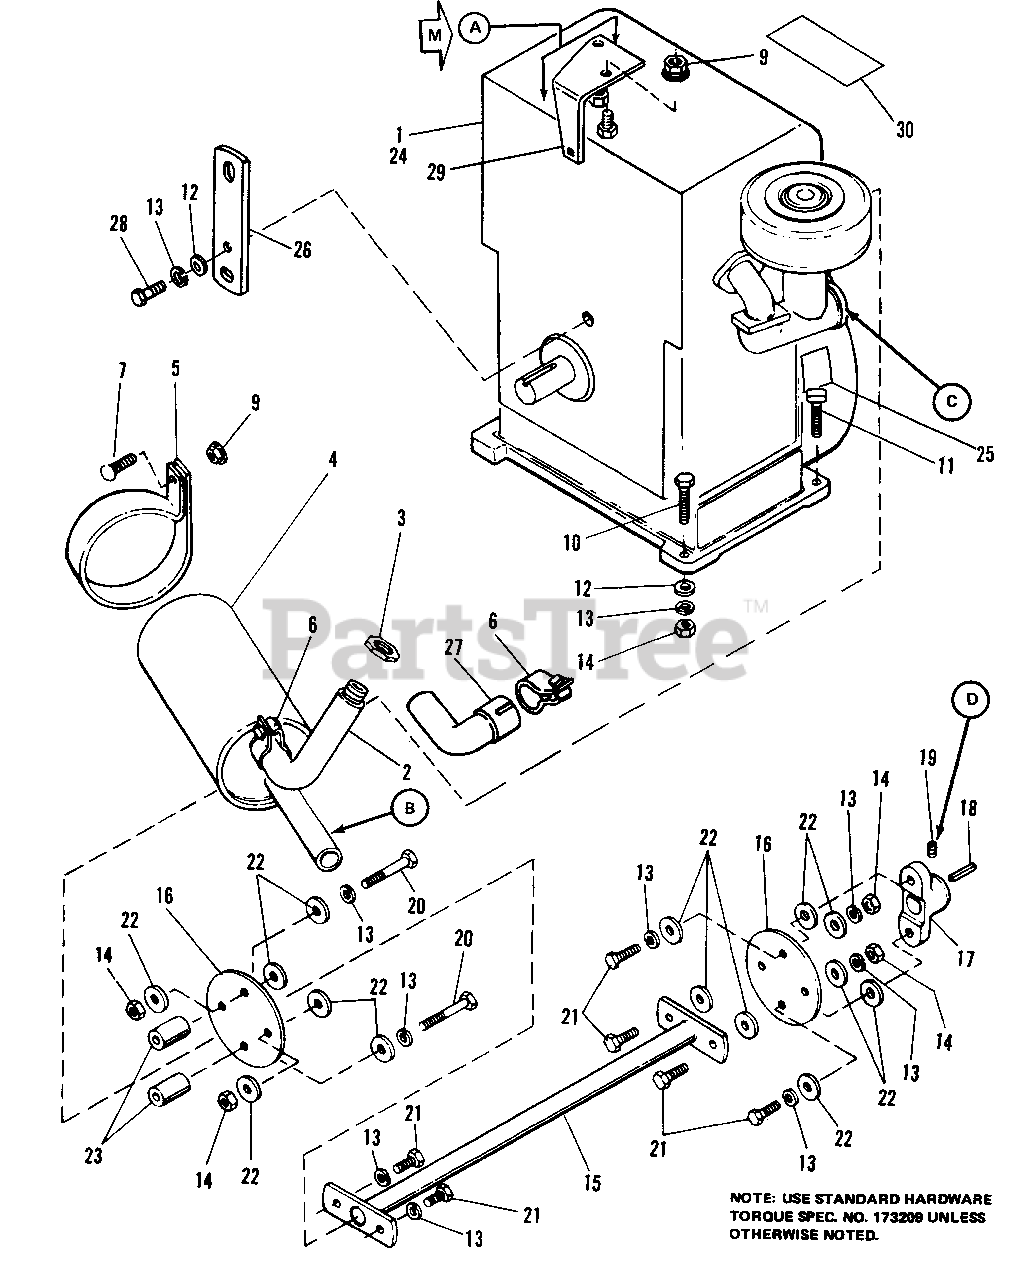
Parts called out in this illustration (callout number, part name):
1	ENGINE, 12 H.P., Kohler (7012 Only)
2	ELBOW & NIPPLE ASSY (7016 Only)
5	STRAP, Muffler
6	CLAMP, Muffler (Quan. 1 used on 7016)
7	CAPSCREW, Hex Hd., 5/16-18 x 1-1/2
8	DECAL, Caution
9	LOCKNUT, Flange, Whizlock 5/16-18 (Quan. 1 used on 7012)
10	CAPSCREW, Hex Hd., 3/8-16 x 1-1/2 (Quan. 2 used on 7016)
11	CAPSCREW, Rect. Hd., 3/8-16 x 1-5/6 (7016 Only)
12	WASHER, 3/8 (Quan. 4 used on 7016)
13	LOCKWASHER, 3/8 (Quan. 12 used on 7016)
14	NUT, Hex, 3/8-16
15	DRIVE SHAFT ASSY
17	FLANGE, Drive Shaft
18	KEY, Drive Shaft
19	SETSCREW, 3/8-24 x 3/8
20	CAPSCREW, Hex Hd., 3/8-16 x 2-1/4
21	CAPSCREW, Hex Hd., 3/8-16 x 1-1/4
22	WASHER, Special
24	ENGINE, 16 H.P., Briggs & Stratton (7016 Only)
25	DECAL, Oil Level Instructions (7016 Only)
26	BRACKET (7012 0nly)
27	ELBOW (7012 Only)
28	CAPSCREW, Hex Hd., 3/8-16 x 7/8 (7012 Only)
29	SUPPORT, Muffler (7016 Only)
